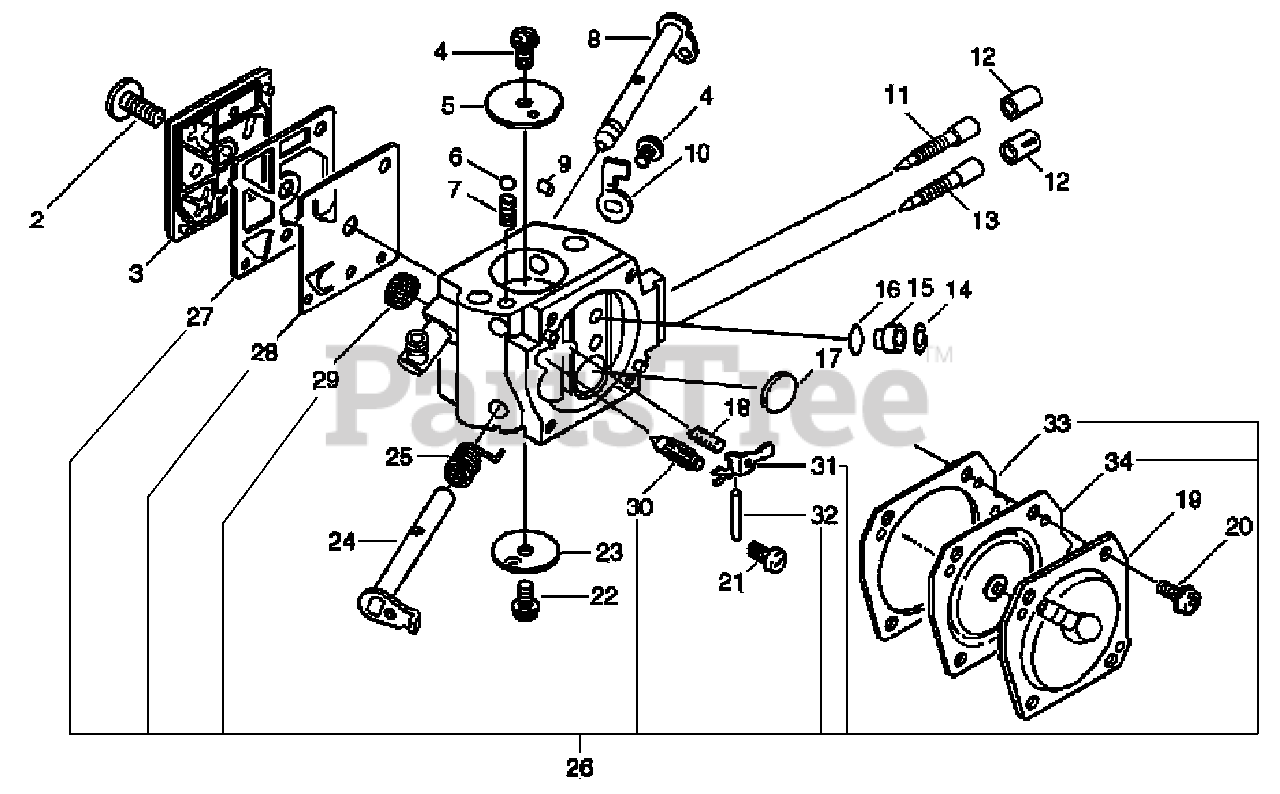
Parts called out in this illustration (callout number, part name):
1	CARBURETOR HDA-216
2	SCREW, PUMP COVER
3	COVER, PUMP
5	VALVE, CHOKE
6	BALL, CHOKE
8	SHAFT, CHOKE
10	STOP, THROTTLE
11	NEEDLE - HIGH SPEED
12	CAP, LIMITER
13	NEEDLE - MIXTURE
14	RING, RETAINING
15	JET, MAIN - 42
16	O-RING
17	PLUG, WELCH
18	SPRING, METERING LEVER
19	COVER, METERING
21	SCREW, METERING LEVER PIN
23	VALVE, THROTTLE
24	SHAFT, THROTTLE
25	SPRING, THROTTLE RETURN
26	REPAIR KIT
27	GASKET, FUEL PUMP
28	DIAPHRAGM, PUMP
29	SCREEN, INLET
30	VALVE, INLET NEEDLE
31	LEVER, METERING
32	PIN, METERING LEVER
33	GASKET, METERING
34	DIAPHRAGM ASSY
